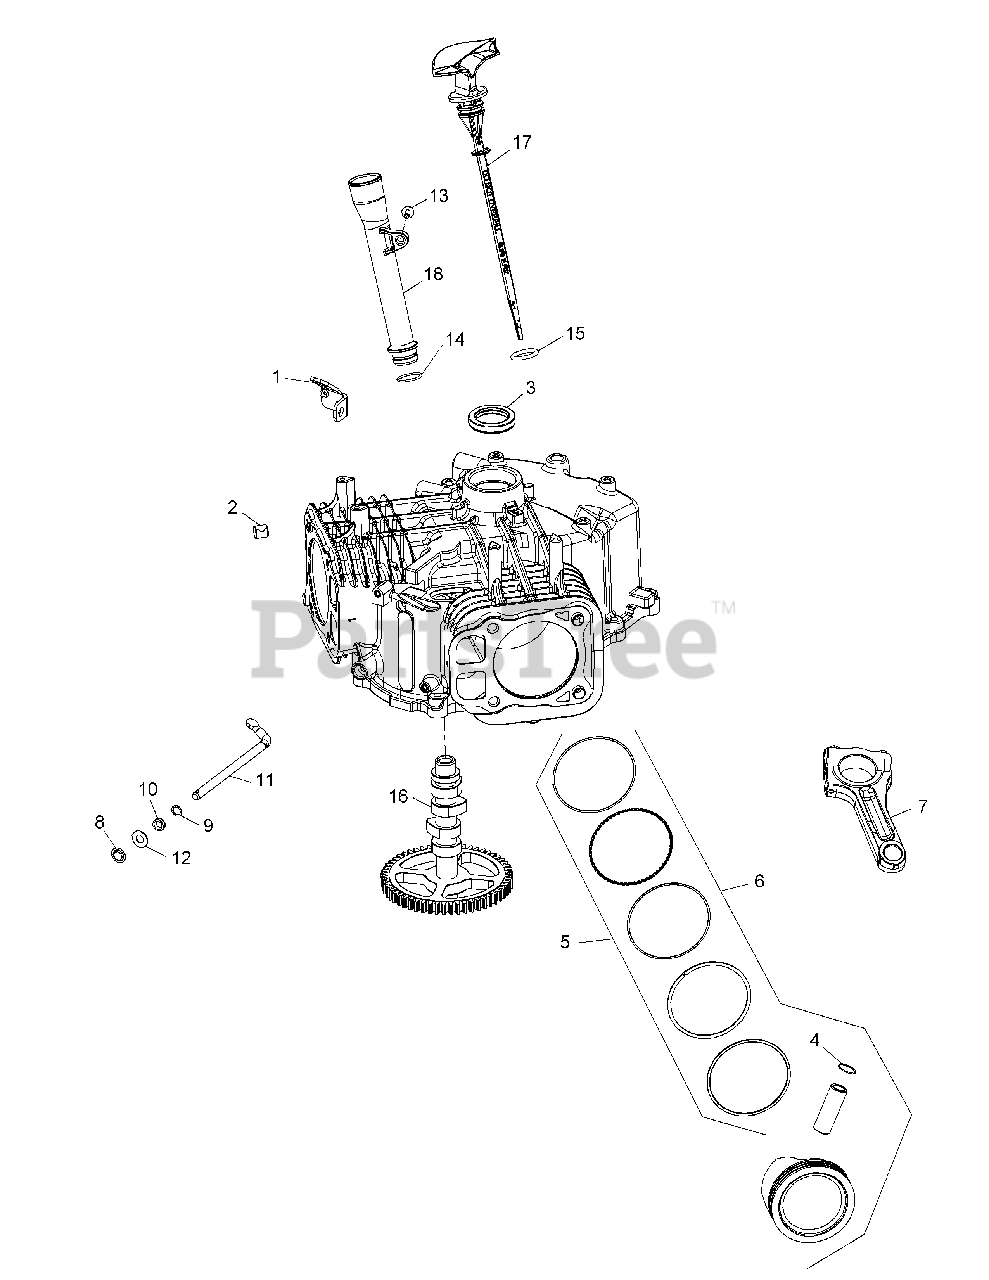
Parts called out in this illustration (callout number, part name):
1	Oil Fill Tube Bracket
3	Oil Seal, 1.78 x 1.26
4	Piston Pin Retainer
5	Piston Ring Set (STD)
5	Piston Ring Set (.08)
5	Piston Ring Set (.25)
5	Piston Ring Set (.50)
6	Piston Kit w/ Ring (STD) (Inc. 4 & 5)
6	Piston Kit w/ Ring (.08)
6	Piston Kit w/ Ring (.25)
6	Piston Kit w/ Ring (.50)
7	Connecting Rod (STD)
7	Connecting Rod (U/S .010) (25mm)
8	Ring Retainer
9	Flat Washer, 11/32"
10	Governor Cross Shaft Seal
11	Governor Cross Shaft
12	Flat Washer, 9 mm
13	Thread Forming Screw
14	O-Ring
16	Camshaft Assembly
17	Dipstick Assembly
18	Oil Fill Tube Assembly
